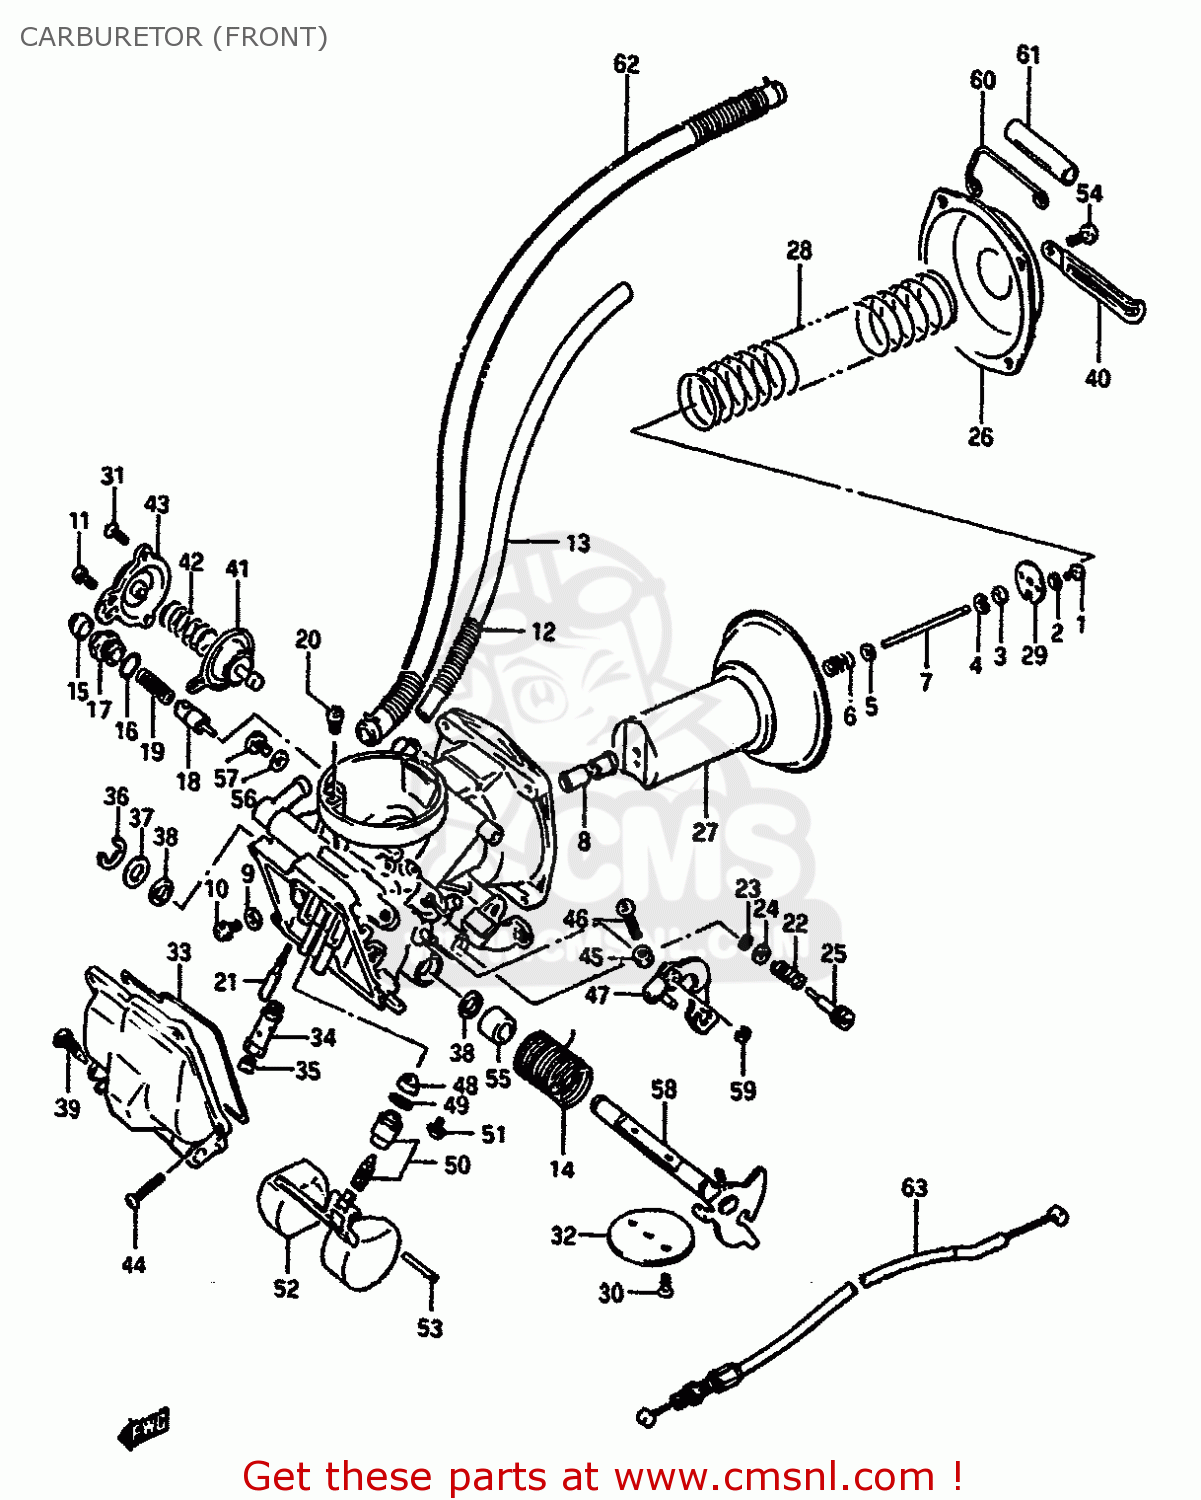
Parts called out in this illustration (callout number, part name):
1	SCREW
2	LOCK WASHER
3	RING
4	CLIP
5	WASHER
6	SPRING
7	NEEDLE,JET
8	JET,NEEDLE(P-2)
9	WASHER,NEEDLE NOZZLE
10	SCREW
11	SCREWM4X0.7X10
12	SPRING
13	HOSE
14	SPRING
15	CAP
16	O RING
17	HOLDER,GUIDE
18	PLUNGER
19	SPRING
20	JET,PILOT
21	JET,PILOT(25)
22	SPRING
23	O RING,PILOT AIR SCREW
24	WASHER
25	SCREW,PILOT AIR
26	COVER,DIAPHRAGM
27	DIAPHRAGM,CARBURETOR
28	SPRING,DIAPHRAGM
29	PLATE
30	SCREW
31	SCREW
32	VALVE,THROTTLE
33	O RING,FLOAT CHAMBER
34	HOLDER,MAIN JET
35	JET
36	E RING
37	GASKET,THROTTLE SHAFT (NAS)
38	SEAL,THROTTLE SHAFT
39	PLUG,DRAIN
40	CLAMP L:35
41	DIAPHRAGM ASSY
42	SPRING
43	COVER
44	SCREW
45	NUT
46	SCREW
47	LEVER,ASSY
48	FILTER
49	O-RING,NEEDLE VALVE
50	VALVE ASSY,NEEDLE
51	SCREW
52	FLOAT
53	PIN,FLOAT
54	SCREW 5X10
55	RING,THROTTLE VALVE
56	WASHER
57	SCREW
58	SHAFT ASSEMBLY,THROTTLE
59	E-RING
60	CLIP
61	HOSE
62	HOSE
63	CABLE,IDLE SYNCRO
